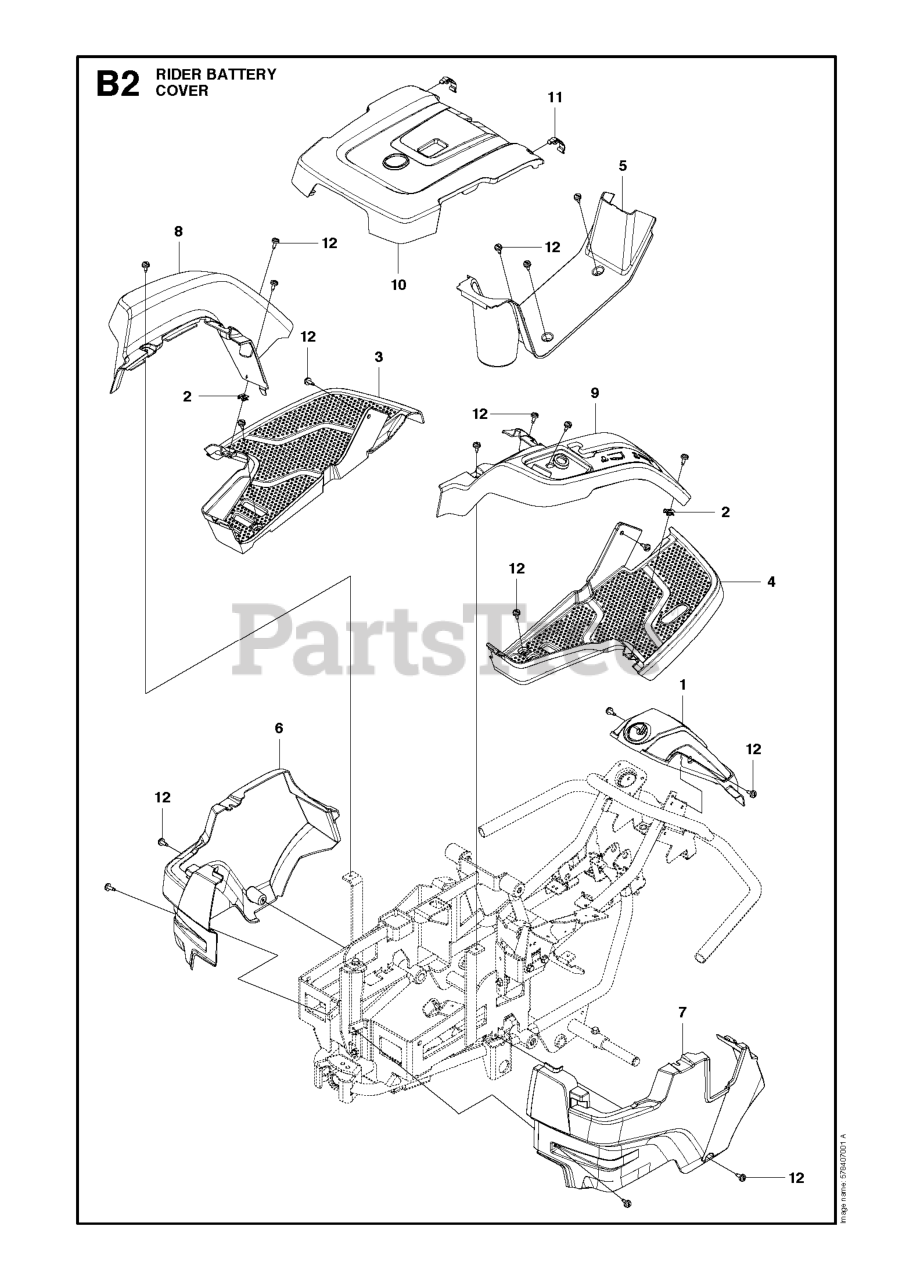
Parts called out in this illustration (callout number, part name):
3	FOOT PLATE
4	FOOT PLATE
11	CLIP GRAY
